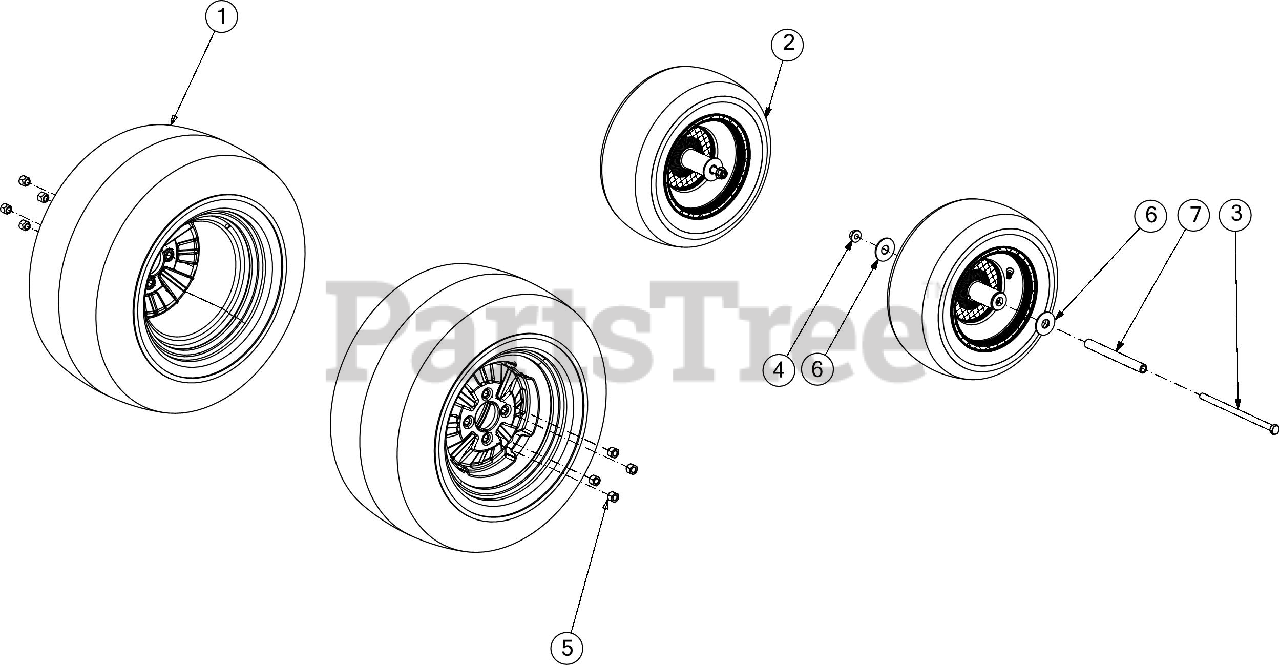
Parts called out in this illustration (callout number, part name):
1	WHEEL ASSEMBLY (24 X 12-12)
2	WHEEL ASSEMBLY (15 X 6.5-8)
3	SCREW 1/2-13 X 9.5 GR5
6	FLAT WASHER .75ID X 2.00D X .10
7	SPACER 51IDX750DX7.38
